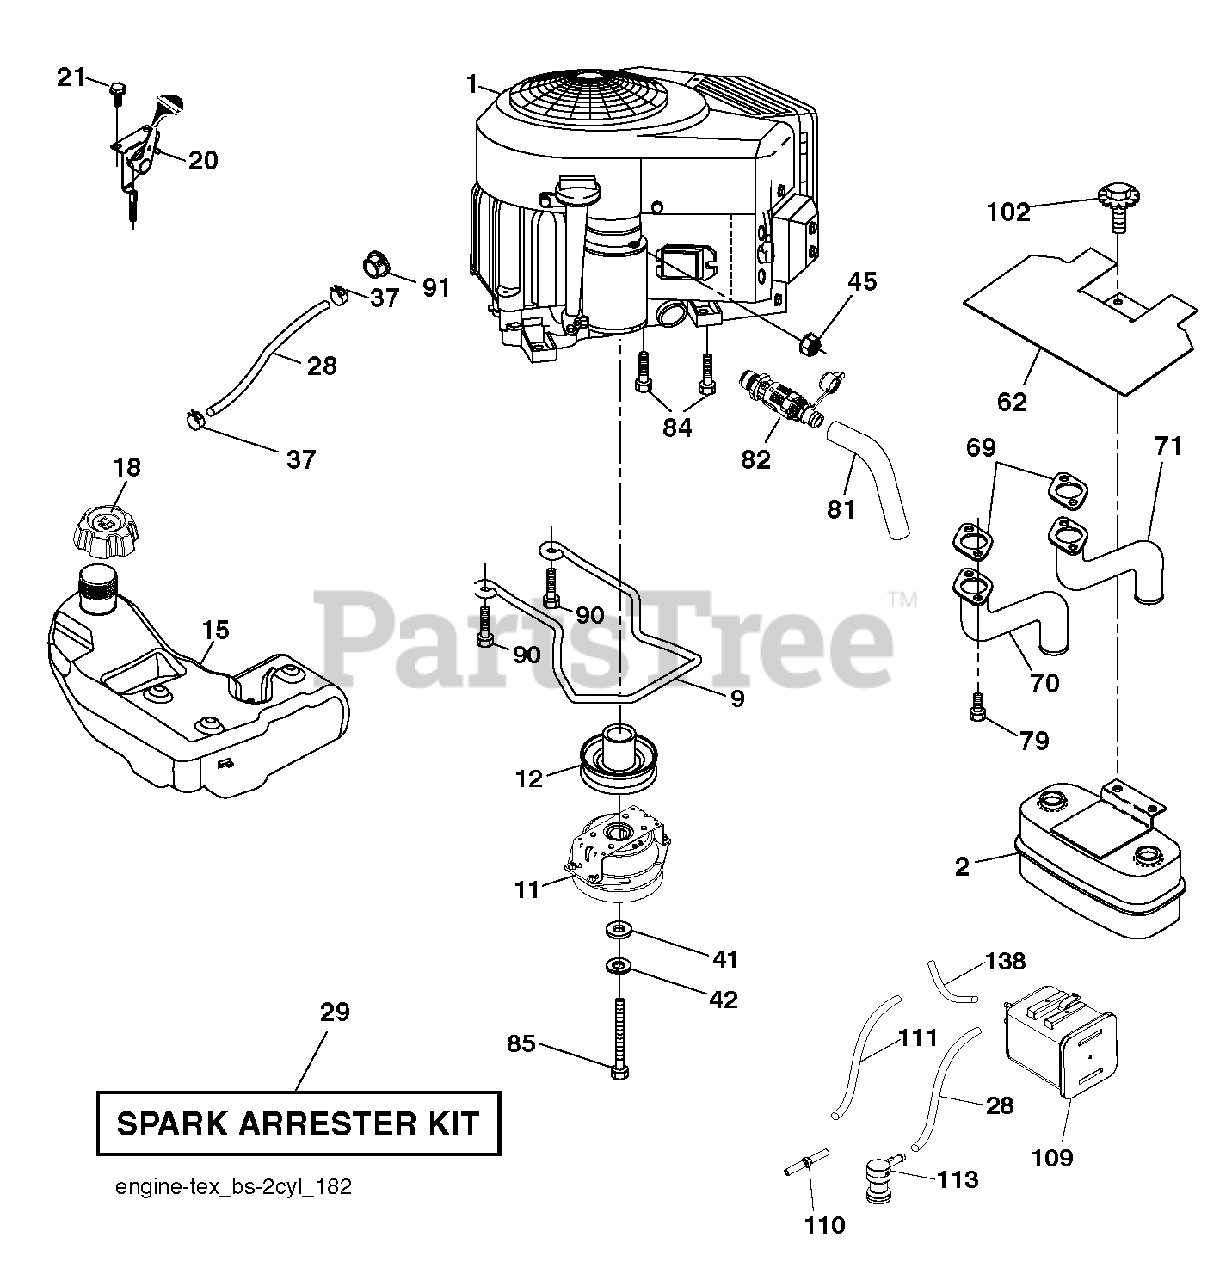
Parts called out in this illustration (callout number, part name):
2	Muffler Assembly, Twin MN
9	KEEPER.BELT.ENG.4.25"2.BLT.431
11	CLUTCH.OGURA.5.0PD.GT1.5A-EH07
12	PULLEY.ENGINE.TUFFTORQ
15	Fuel Assembly Tank, 3 Gallon
18	CAP ASSY FUEL 3" GRAY
20	THROTTLE.COBRA.38"READSTART.BK
21	SCREW.#10 X 0.750.BOS
28	LINE.FUEL.64"REAR.EMIS
29	KIT.SPARK ARRESTOR 794945 B&S
37	HOSE CLAMP
42	WASHER 7/16 LOCK
45	NUT
62	SHIELD.HEAT.MUFFLER
69	GASKET.MUFFLER
70	EXHAUST.TUBE.LH.BS/TWIN
71	EXHAUST.TUBE.RH.B&S.TWIN.INTEK
79	SCREW.SOCKET.HEAD.5/16-18
81	TUBE, DRAIN OIL ASM.
82	VALUE.OIL.DRAIN
84	SCREW.3/8-16
85	BOLT.HEX.7/16-20X3.75.GR5.RED
90	SCREW 3/8-16X1
91	BUSHING.1.375OD
102	SCREW
109	CANNISTER, CARBON
110	VALVE.ASM.ANTI-SLOSH
111	RP PURGE LINE
113	VALVE.SLANT.CARTRDG.90 DEG.TEX
138	PURGE.LINE.36"REAR.CALIFORNIA
